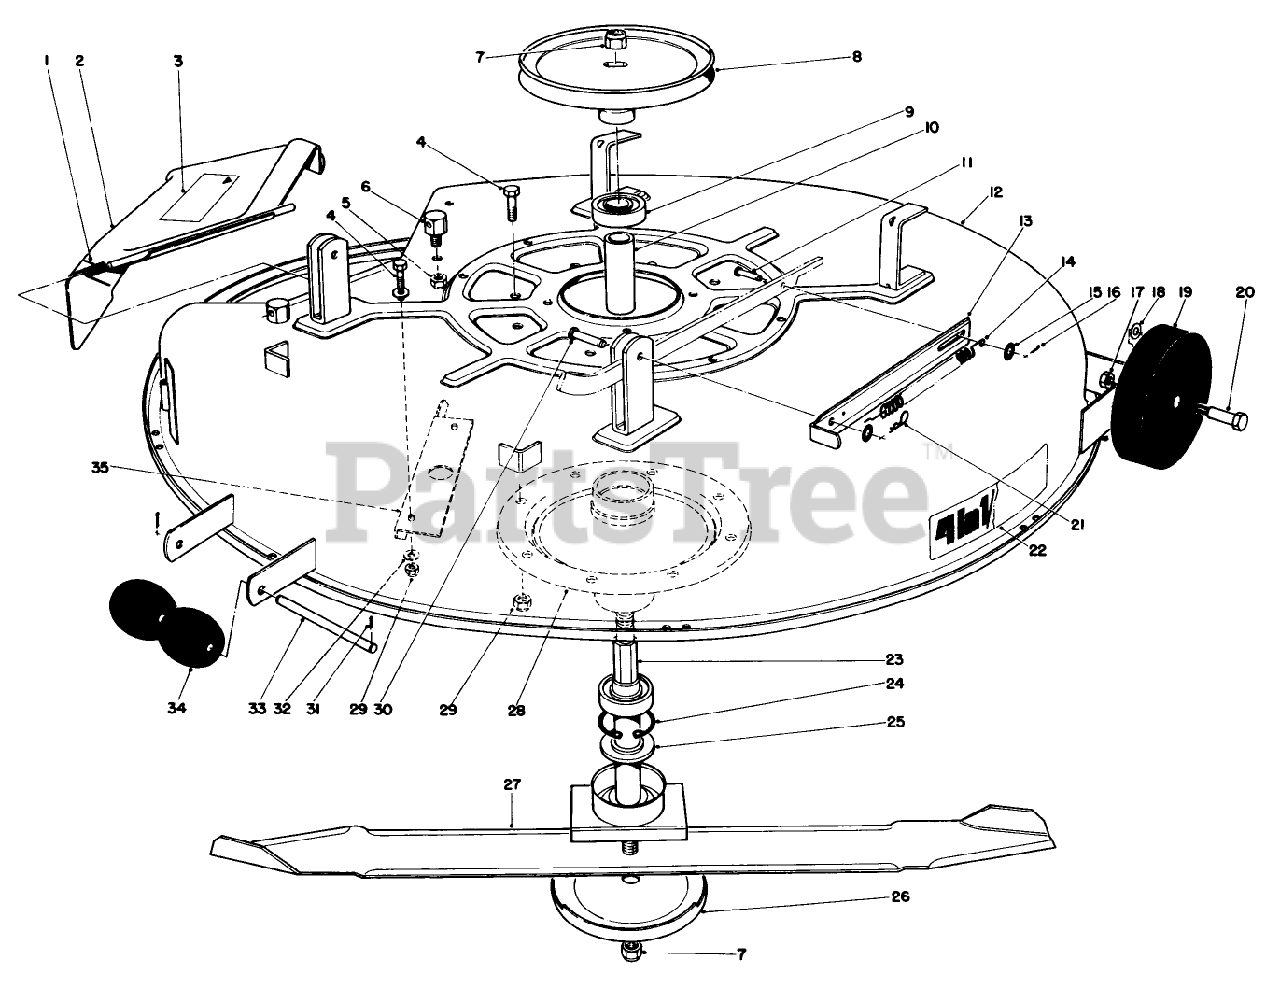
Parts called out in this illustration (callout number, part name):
1	SPRING
2	DEFLECTOR ASM
4	SCREW-HH
5	NUT-LOCK, SIDE
6	POST-PIVOT
7	NUT-SPECIAL
9	BEARING-BALL
11	PIN-CLEVIS
15	WASHER-FLAT
16	PIN-COTTER
18	WASHER-FLAT
21	PIN-COTTER
23	SPINDLE SHAFT WA
25	SPACER-SPINDLE
29	NUT-LOCK, NI
30	PIN-CLEVIS
31	PIN-COTTER
32	WASHER-PLAIN
34	ROLLER
